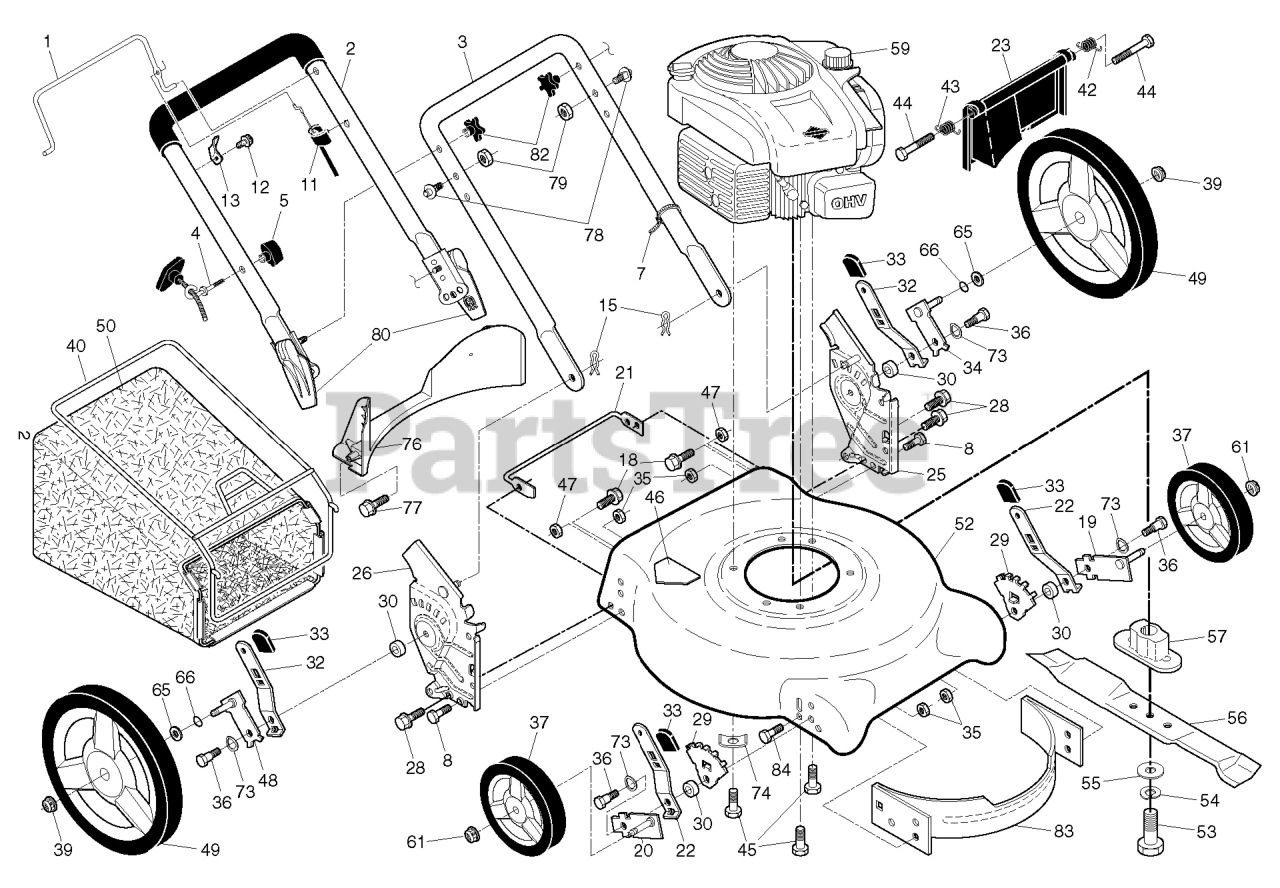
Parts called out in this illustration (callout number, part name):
1	BAIL.OVER.MOLD.ERGO.MZR.ORANGE
2	HDLE.ASM.UP.3POS.ADJ.BKT.GRIP
3	HANDLE.LOWER.21.NB.GREY
4	GUIDE.ROPE.BLK.ZINC.CHROM
5	T-KNOB.NEW ROPE GUIDE
7	TIE GUIDE
8	BOLT.FIN.HEX.5/16-18X3/4
11	CABLE.ASM.ZONE.CONTROL
13	BRACKET.UPSTOP.RT
15	HAIRPIN COTTER
18	SCREW 1/4X20
19	AXLE ARM ASSY FRONT LH
20	AXLE ARM ASSY FRONT RH
21	FOOT.GUARD.21.DOM/FGD.CE.10
22	SELECTOR SPRING, FRONT
23	DOOR.REAR.21.DOMED.498
25	BRACKET.ASM.HAND.HW.21.LT.GREY
26	BRACKET.ASM.HAND.HW.21.RT.498
28	SCREW 14-20 X 5/8
29	WHEEL ADJ BRACKET FRONT
30	SPACER.HEIGHT.ADJUSTER
32	SPRING.SEL.22.ECON.HI-WHL.RATO
33	SELECTOR KNOB
34	AXLE ARM ASSY REAR LH
35	NUT.FLANGE.HEX.5/16X18.BLACK
36	SHOULDER BOLT 5/16-18
37	WHEEL AND TIRE ASSY, REAR
39	NUT.HEX.FLANGE.3/8-16.LOCKNUT
40	FRAME.BAG.21.REAR.DOMED.PUSH
42	SPRING.LH.22.REAR.DOOR.EZ.EMPT
43	SPRING.RH.22.REAR.DOOR.EZ.
45	BOLT 3/8-16X1-1/8
46	DECAL.INTERNATIONL.CUTFINGER
48	AXLE ARM ASSY REAR RH
49	WHEEL.12X1.75H.3.SPOKE.RADIAL
50	GBAG.24710090.GENERIC H-GRY498
52	KIT.HSG.21RD.DOME.ORG.CE
53	SCREW, HEX HD 3/8-24 X 1-3/8
54	LOCKWASHER
55	WASHER,HARDEN
56	BLADE.21.PUSH
57	ADAPTOR.BLADE.7/8
61	NUT.HEX.FLANGE.3/8-16.LO(3 2)
65	WASHER.FLAT.1/2
66	O-RING..070X.487.NEOPRENE
73	WASHER.CURVED.CYLINDRICAL
74	WASHER.ENGINE.BZP
76	BAFFLE.REAR.PLASTIC.21.RD.ECON
77	SCREW.HX.13X.750
78	STUD.QUICK.ADJUST
79	NUT.LOCK.5/16-18
80	QUICK.ASM.RELEASE.BLACK
82	KNOB.HANDLE.PLASTIC.STAR.BLACK
83	BAFFLE.FRONT.21.DOME.US
84	BOLT.5/16HEX.WHS.HD
